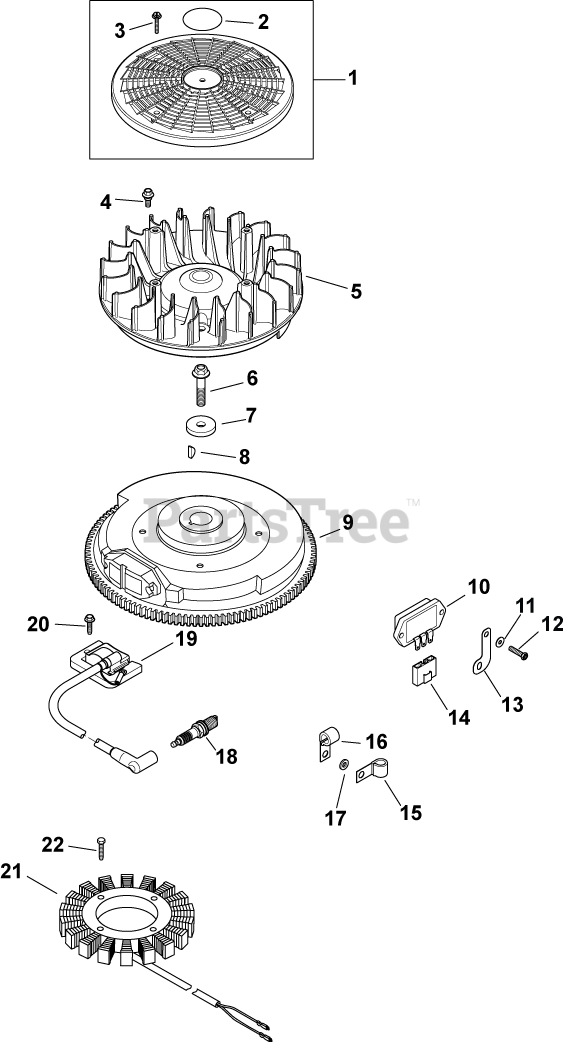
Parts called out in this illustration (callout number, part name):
1	KIT, GRASS SCREEN
2	DECAL, GRASS SCREEN USE 24 113 499-S
3	SCREW, FLG SEMS M4X.7X25
4	BOLT, SHOULDER
6	SCREW, FLG M10X1.5X45 - (#25086361S)
7	WASHER, FLAT 13/32"
8	KEY, 3/16" X 5/8"
10	REGULATOR/RECTIFIER
11	WASHER, FLAT 3/16"
12	SCREW, PHL HD #11-16X7/8"
13	BRACKET, GROUND STRAP USE 24 518 12-S
14	CONNECTOR
15	CLIP, TUBE & WIRING (KM)
16	CLIP, CABLE
17	WASHER, FLAT 1/4" (O.D. 1/2")
18	PLUG, SPARK (STD)
19	KIT, MODULE IGNTN (CDI FIXED)
20	SCREW, FLG THD FRM M5X.8X20-(#25086399S)
21	KIT, 15 / 20 AMP STATOR
22	SCREW, M5X0.8X25 - (#25086402S)
2546807-S	WASHER, FLAT 7/32"
